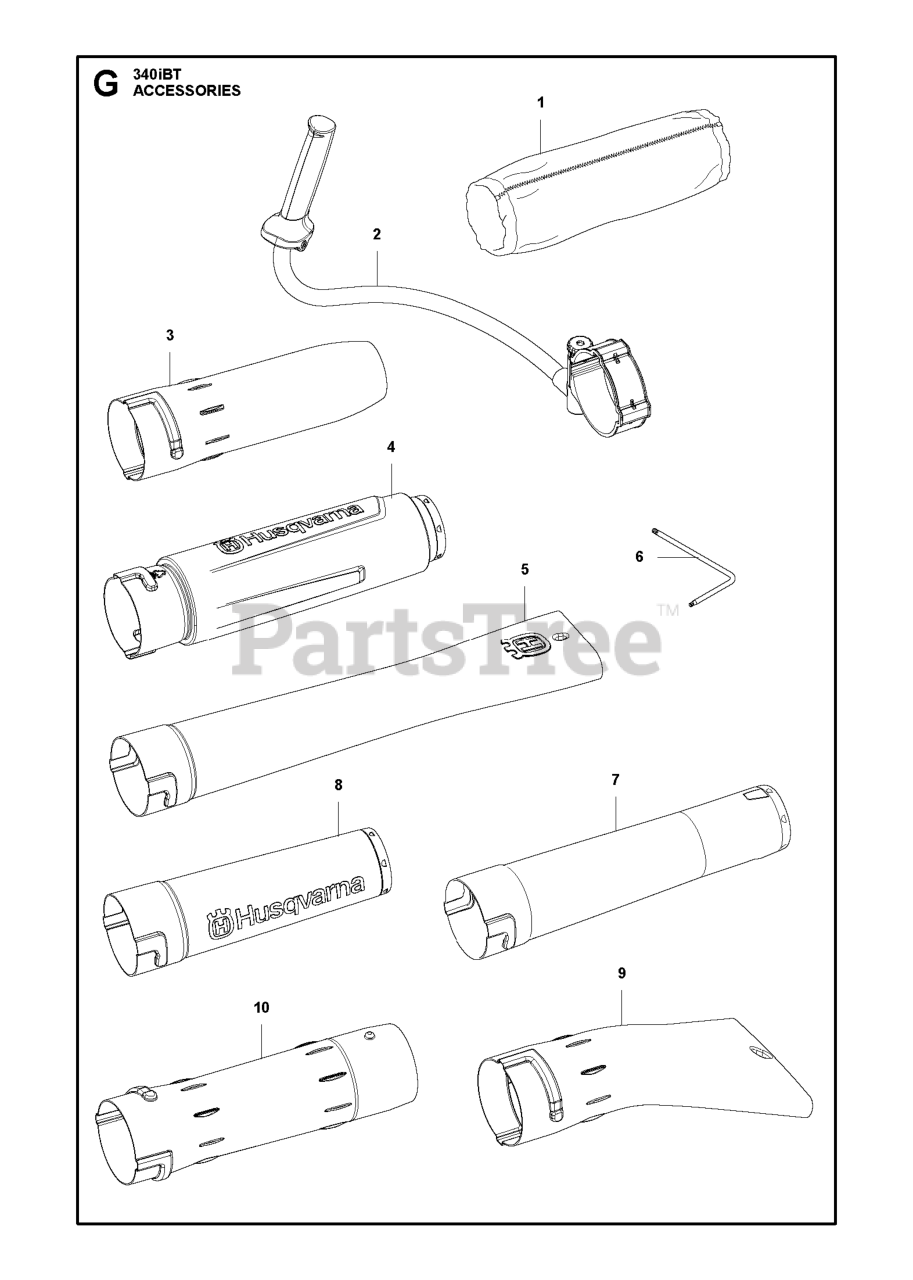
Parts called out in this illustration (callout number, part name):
1	SLEEVE TUBE
2	HANDLEBAR ASSY
4	TUBE ASSY NOZZLE SILENCER
5	BLOWER NOZZLE FOR 320IB
7	TUBE ASSY NOZZLE 536LIBX
9	NOZZLE FLAT
10	PIPE STRAIGHT
